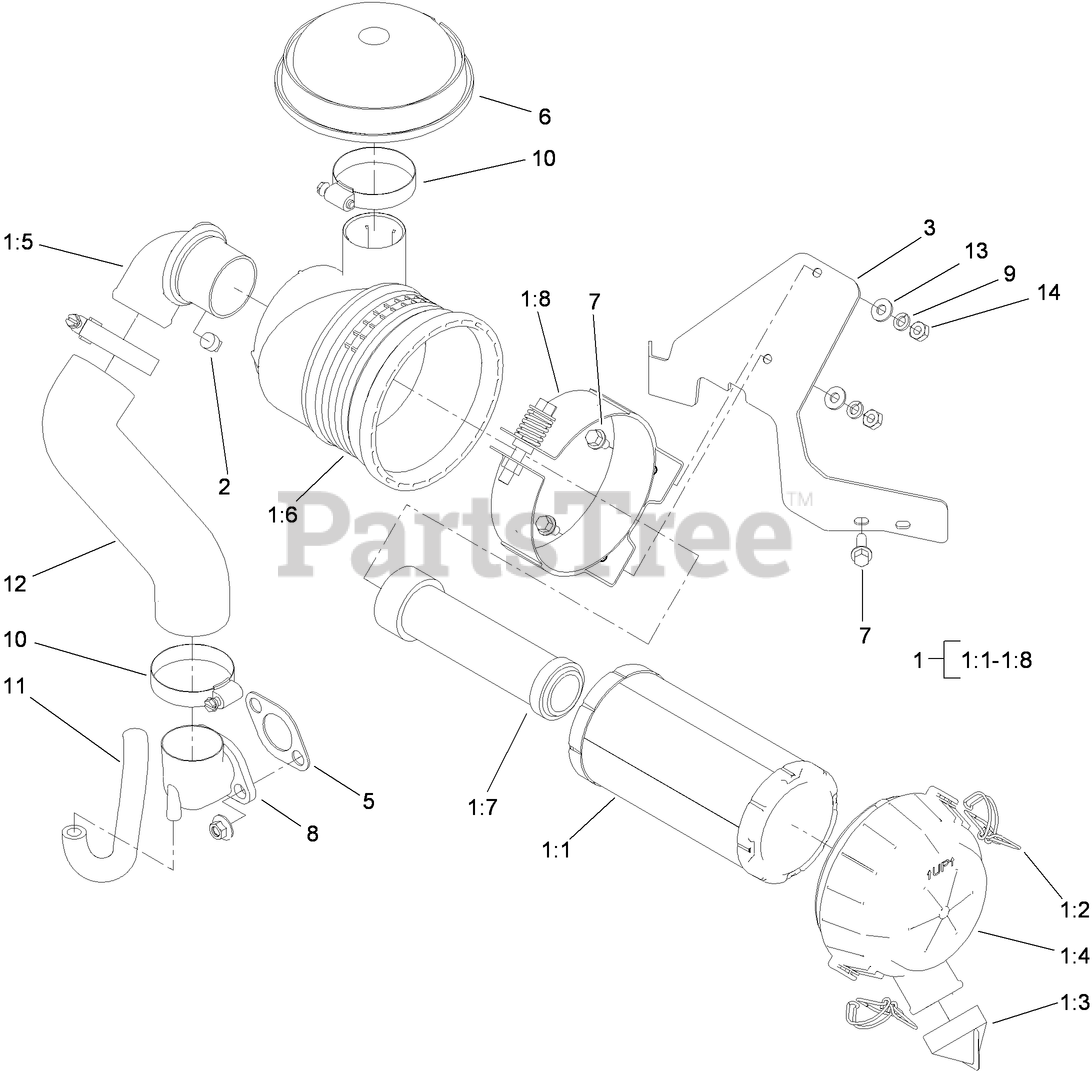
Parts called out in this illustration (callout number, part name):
1	AIR CLEANER ASM
1:1	ELEMENT-FILTER, AIR
1:2	CLIP-CLEANER, AIR
1:3	VALVE-EJECTOR, DUST
1:4	COVER
1:5	TUBE ASM
1:6	HOUSING
1:7	FILTER-SAFETY
1:8	MOUNTING BRACKET ASM
3	BRACKET-CANISTER
5	GASKET-CLEANER, AIR
6	HOOD-1.75" AIR INTAKE
7	BOLT-FLANGED
8	PIPE-INTAKE
9	WASHER
10	CLAMP-HOSE
12	TUBE (INTAKE)
13	WASHER
14	NUT-HEX
